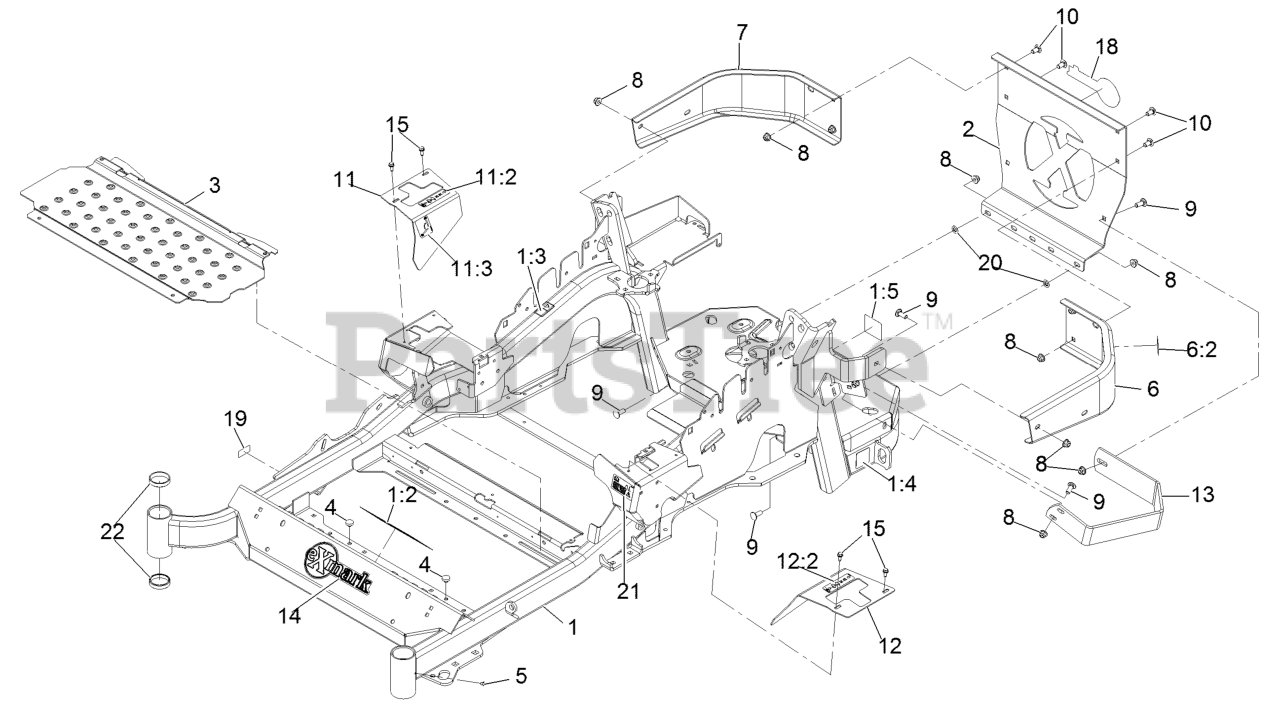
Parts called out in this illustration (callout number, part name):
1	Mainframe ASM
1:2	Decal-Danger
1:3	Decal-Warning, Hot Surface
1:4	Decal-Hazard, Pinched Finger
1:5	Decal-Spark Arrester
2	Plate,Rear Guard
6	LH Bumper ASM
6:2	Decal-Warning, Hot Surface
7	Bumper-RH
8	Nut-Nyloc 3/8-16 Flg
9	Bolt-Carriage 3/8-16 X 1
10	Bolt-Carriage 3/8-16 X 3/4
11	RH Motion Control Cover ASM
11:2	Decal-Control, Motion
11:3	Decal-Park Brake, Ce
12	LH Motion Control Cover ASM
12:2	Decal-Control, Motion
13	Guard-Muffler
14	Decal-Exmark Logo
15	Screw-HWH 1/4-20 X .62
18	Decal-Exmark Logo
19	Decal-Patent
20	Nut-Push 3/8-16
21	Decal-Fuel Fill, Ce
22	Cup-Bearing Tapered Roller
